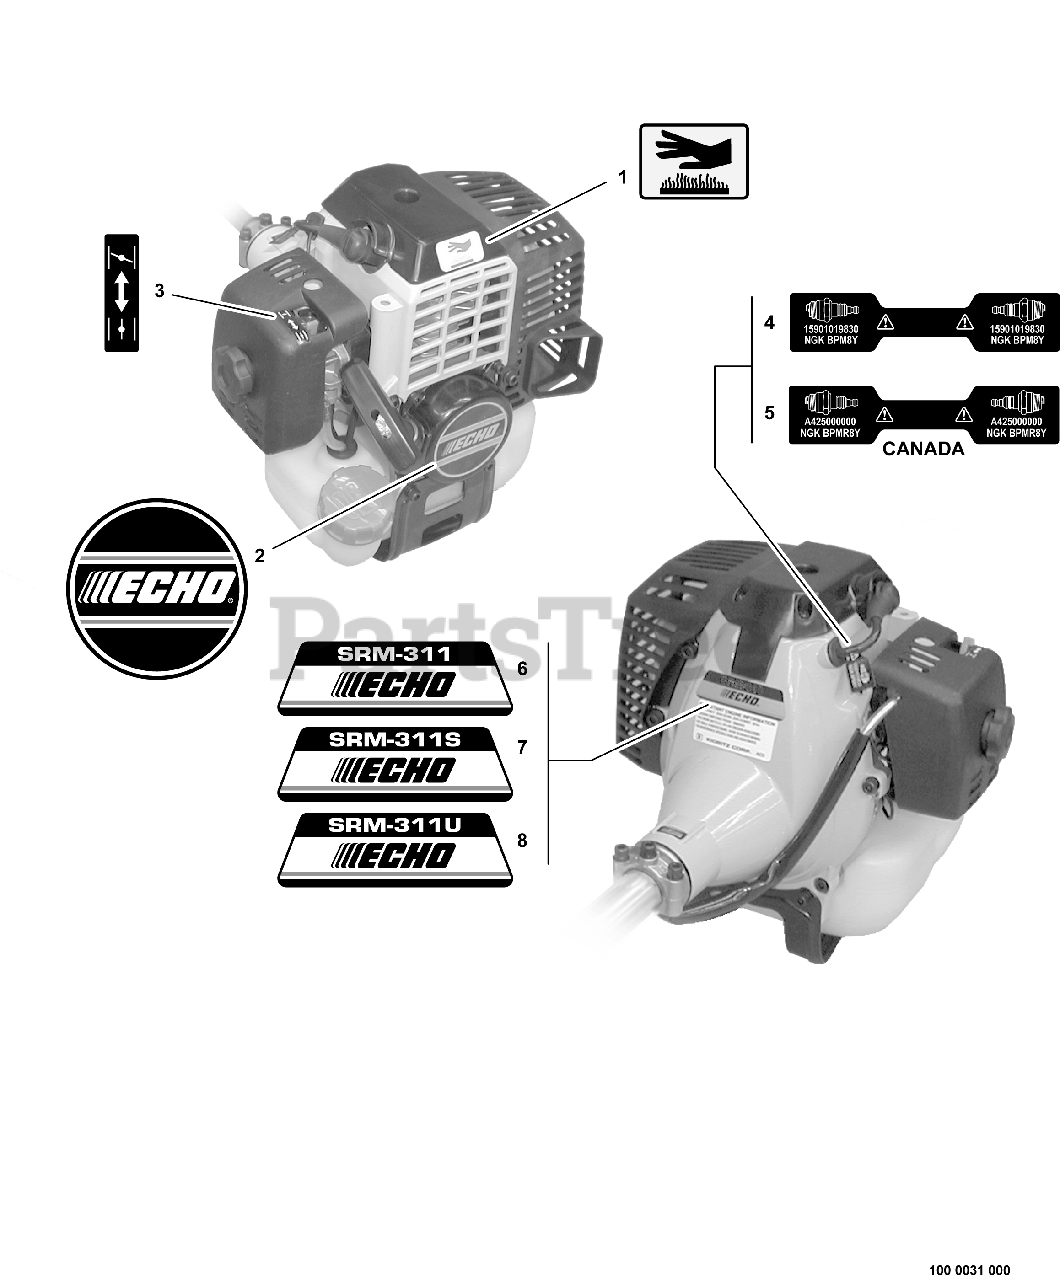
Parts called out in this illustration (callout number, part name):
1	LABEL - HOT SURFACE
2	LABEL - ECHO
3	LABEL - CHOKE
4	LABEL - SPARK PLUG -- BPM-8Y
5	LABEL - SPARK PLUG -- BPMR-8Y
6	LABEL - MODEL SRM-311
7	LABEL - MODEL SRM-311S
8	LABEL - MODEL SRM-311U
